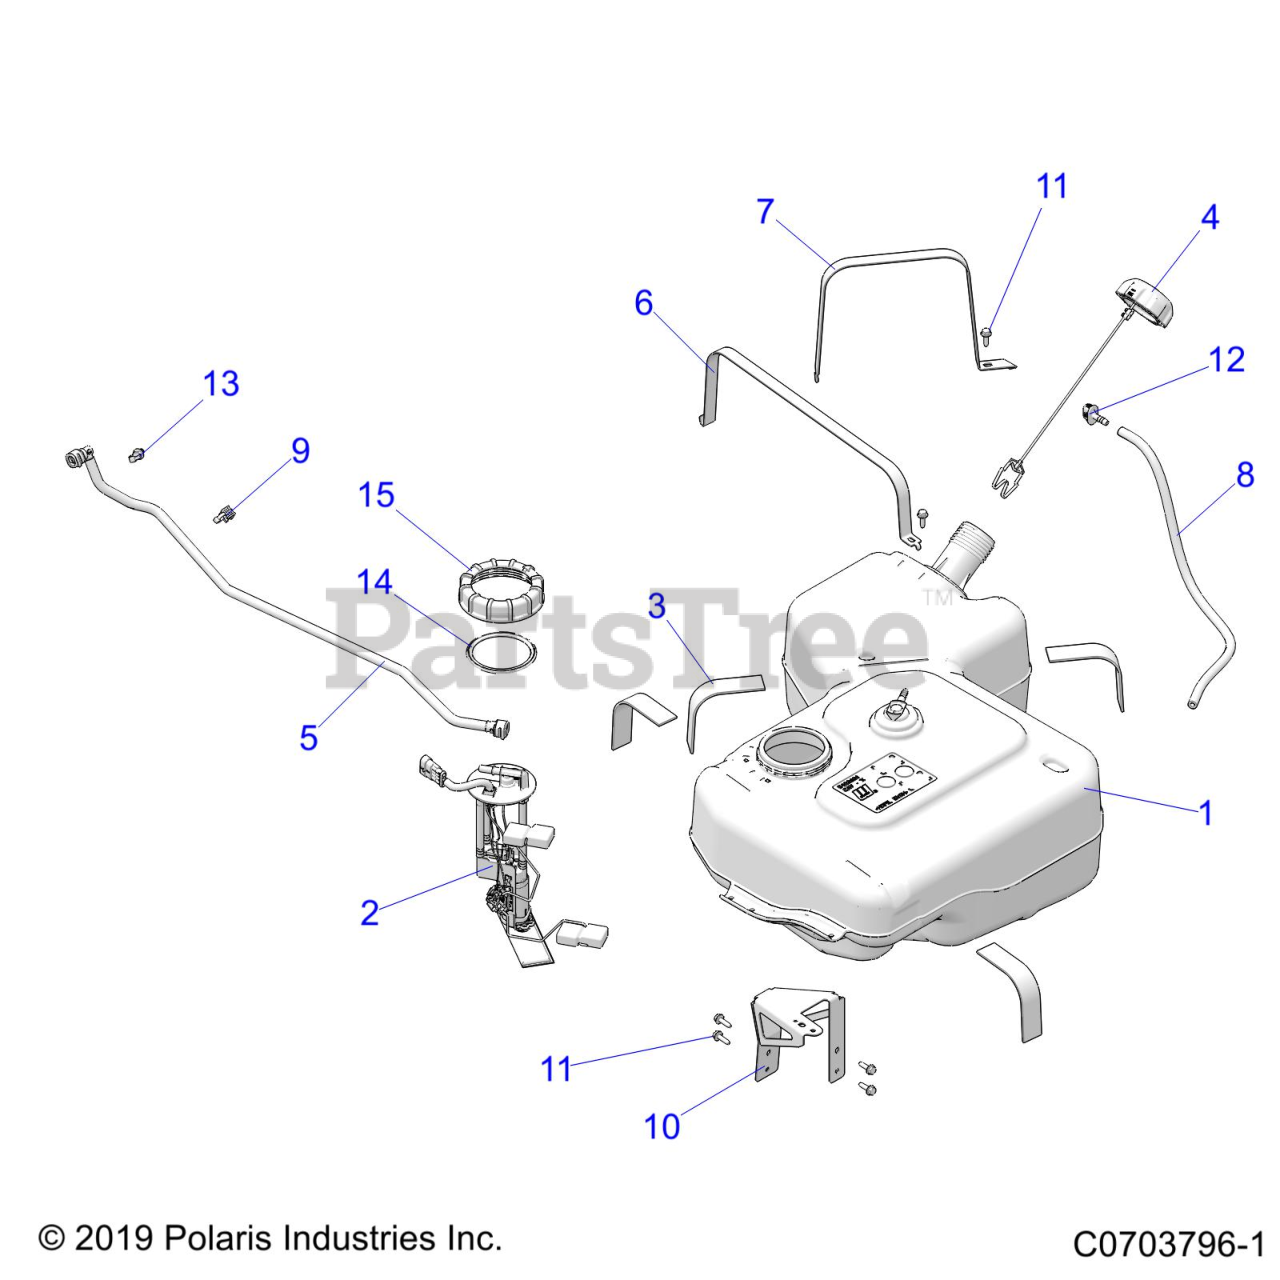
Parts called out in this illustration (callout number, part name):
1	ASM-FUEL TANK
2	ASM-FUEL PUMP
3	PAD, BATTERY
4	CAP-GAS TANK,TETHER
5	ASM-FUEL LINE
6	BRKT-TANK,STRAP,INSIDE,GALV
7	BRKT-TANK,STRAP,OUTSIDE,GALV
8	FUEL LINE-54 CENTIMETRS
9	CLIP-EDGE,SIDE W/STRAP
10	BRKT-FUEL TANK,SUPPORT,BLK
11	SCR-M6X1.0X20,HXHD,FLG,TDFM,BL
12	FITTING-VENT LINE
13	CLIP-ROUTING
14	GASKET-PFA,RIBBED
15	NUT-MASON JAR
